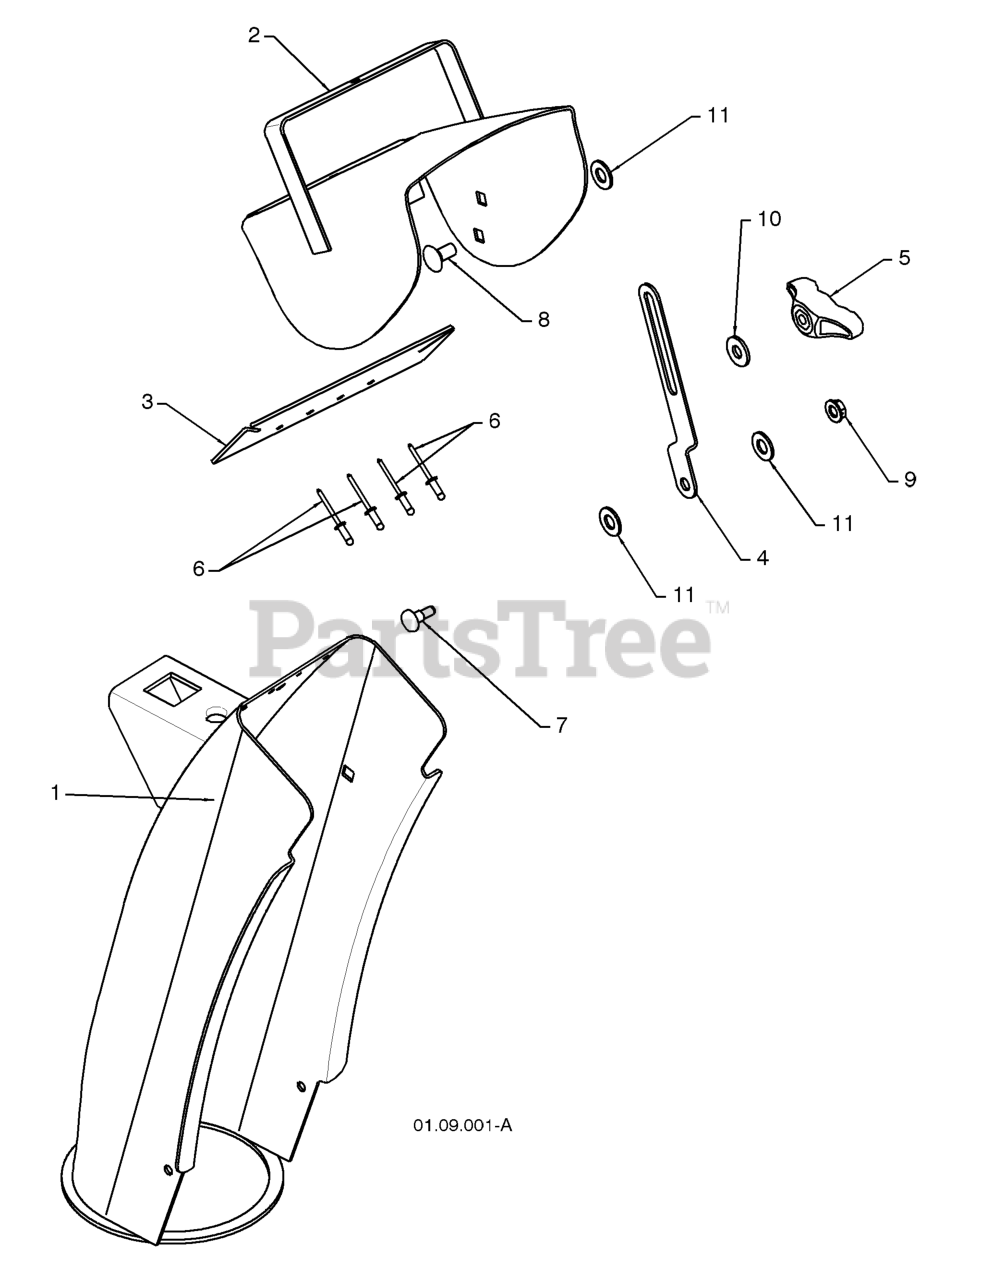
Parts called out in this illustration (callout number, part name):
1	CHUTE ASSEMBLY
2	DEFLECTOR.WELDMENT.PNT.ORANGE
3	SEAL.DEFLECTOR
4	STRAP, CHUTE
5	KNOB, DEFLECTOR
6	RIVET BLIND
7	SHOULDER BOLT
8	BOLT
9	NUT.HEX.FLANGE.1/4
10	WASHER.20X8.5
11	WASHER, NYLON FRICTION
